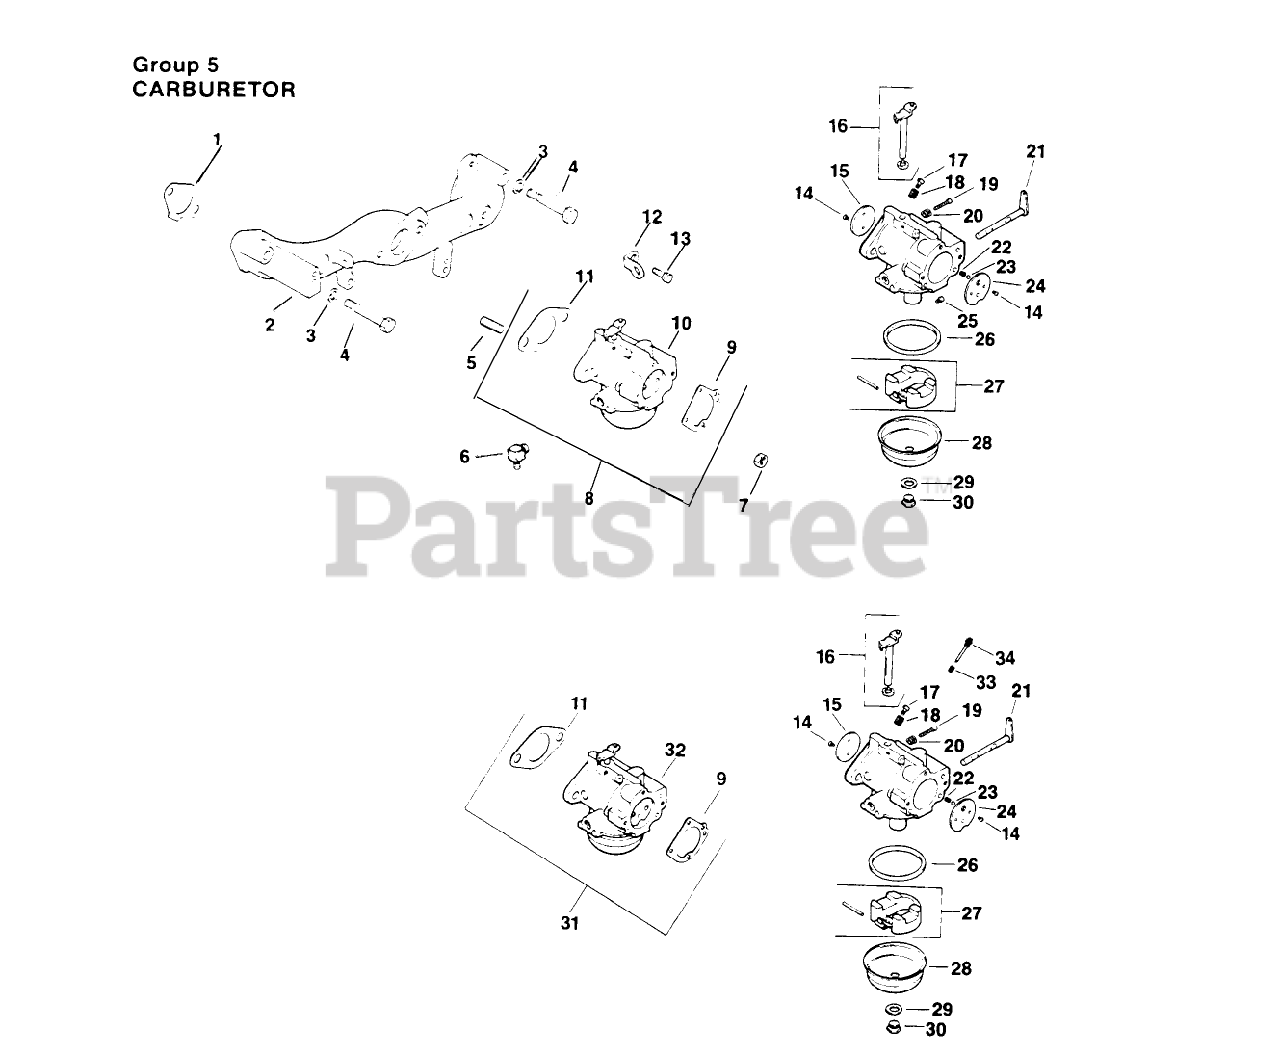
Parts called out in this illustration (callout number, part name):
1	Gasket-Intake
2	Manifold-Intake
3	Washer
4	Screw
6	Connector-Hose
8	Carburetor Kit w/Linkage (Incl. Ref. #7-9,14-30)
9	Gasket-Elbow
10	Carburetor Assembly Ref.
11	Gasket
12	Strap Lifting
13	Screw
14	Screw-Throttle Plate (Only On: 72042,72043,72062,72063)
15	Plate-Throttle
16	Shaft Assembly
17	Needle-Idle Fuel Adj.
19	Screw-Idle Speed Adj.
20	Spring-Idle Speed
21	Lever-Choke
22	Spring-Choke Friction
23	Ball-Choke Friction
24	Plate-Choke
25	Jet-Main
26	Gasket
27	Kit-Float
28	Bowl-Fuel
29	Gasket-Retainer Screw
30	Screw-Bowl Retainer
31	Kit-Carburetor w/Gasket
32	CARburetor Assembly For Information Only
34	Needle-Main Fuel
